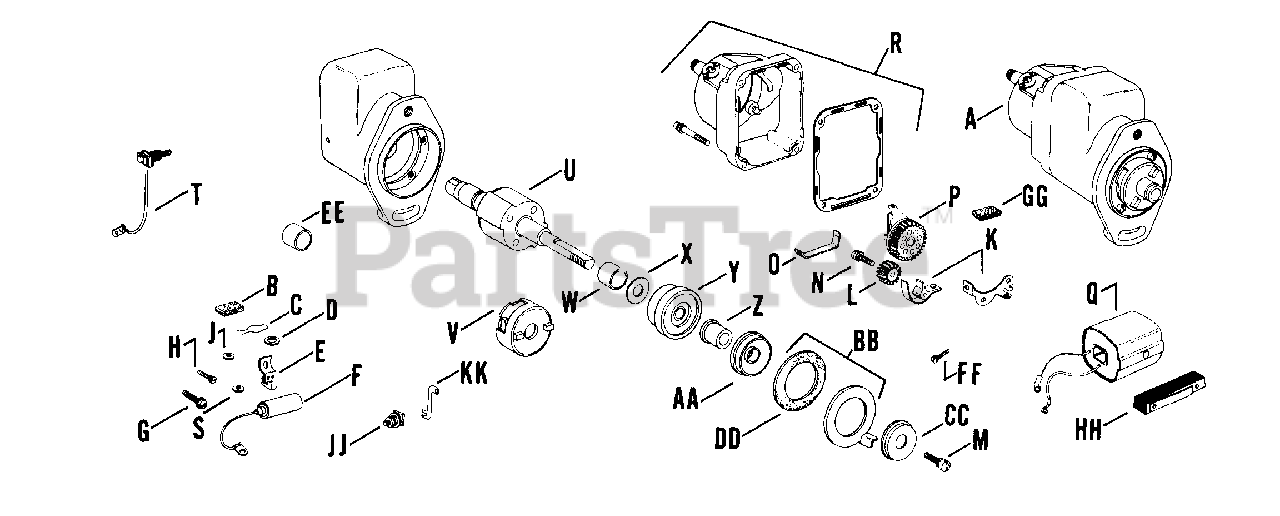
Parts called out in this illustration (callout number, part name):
A	MAGNETO - DISCONTINUED
C	LOCK - DISCONTINUED
F	CONDENSER - DISCONTINUED
L	GEAR - DISCONTINUED
P	ARM - DISCONTINUED
Q	COIL - DISCONTINUED
T	UNIT - DISCONTINUED
U	ROTOR - DISCONTINUED
Y	HOUSING - DISCONTINUED
AA	SEAL - DISCONTINUED
BB	STOP - DISCONTINUED
CC	OIL SLINGER - DISCONTINUED
DD	GASKET - DISCONTINUED
GG	FELT - DISCONTINUED
JJ	UNIT - DISCONTINUED
